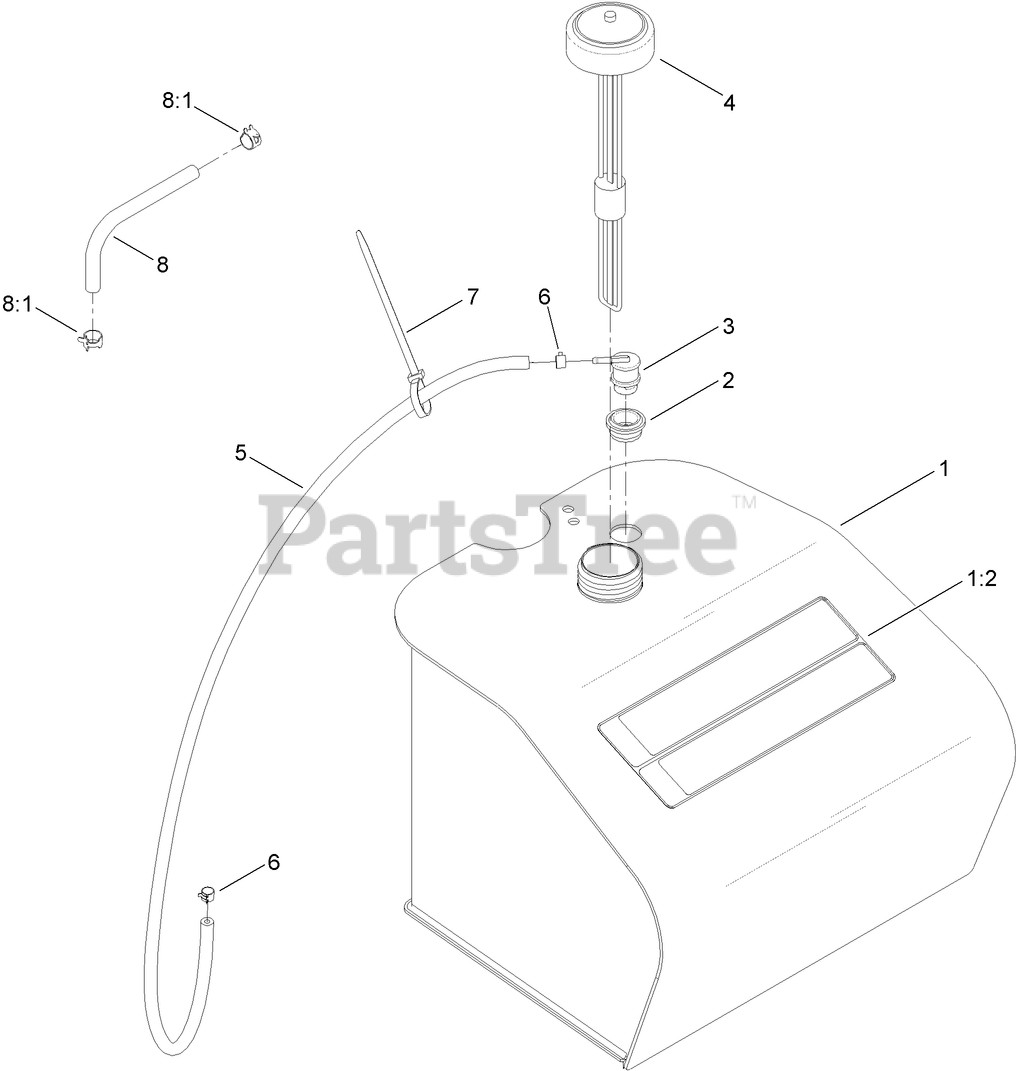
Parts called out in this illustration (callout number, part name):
1	TANK ASM
1:2	DECAL-OPERATION
2	GROMMET
3	VALVE-VENT, FUEL
4	GAUGE-FUEL
5	HOSE-FUEL
6	CLAMP-HOSE
7	TIE-PLASTIC
8	FUEL HOSE KIT
8:1	CLAMP-HOSE
